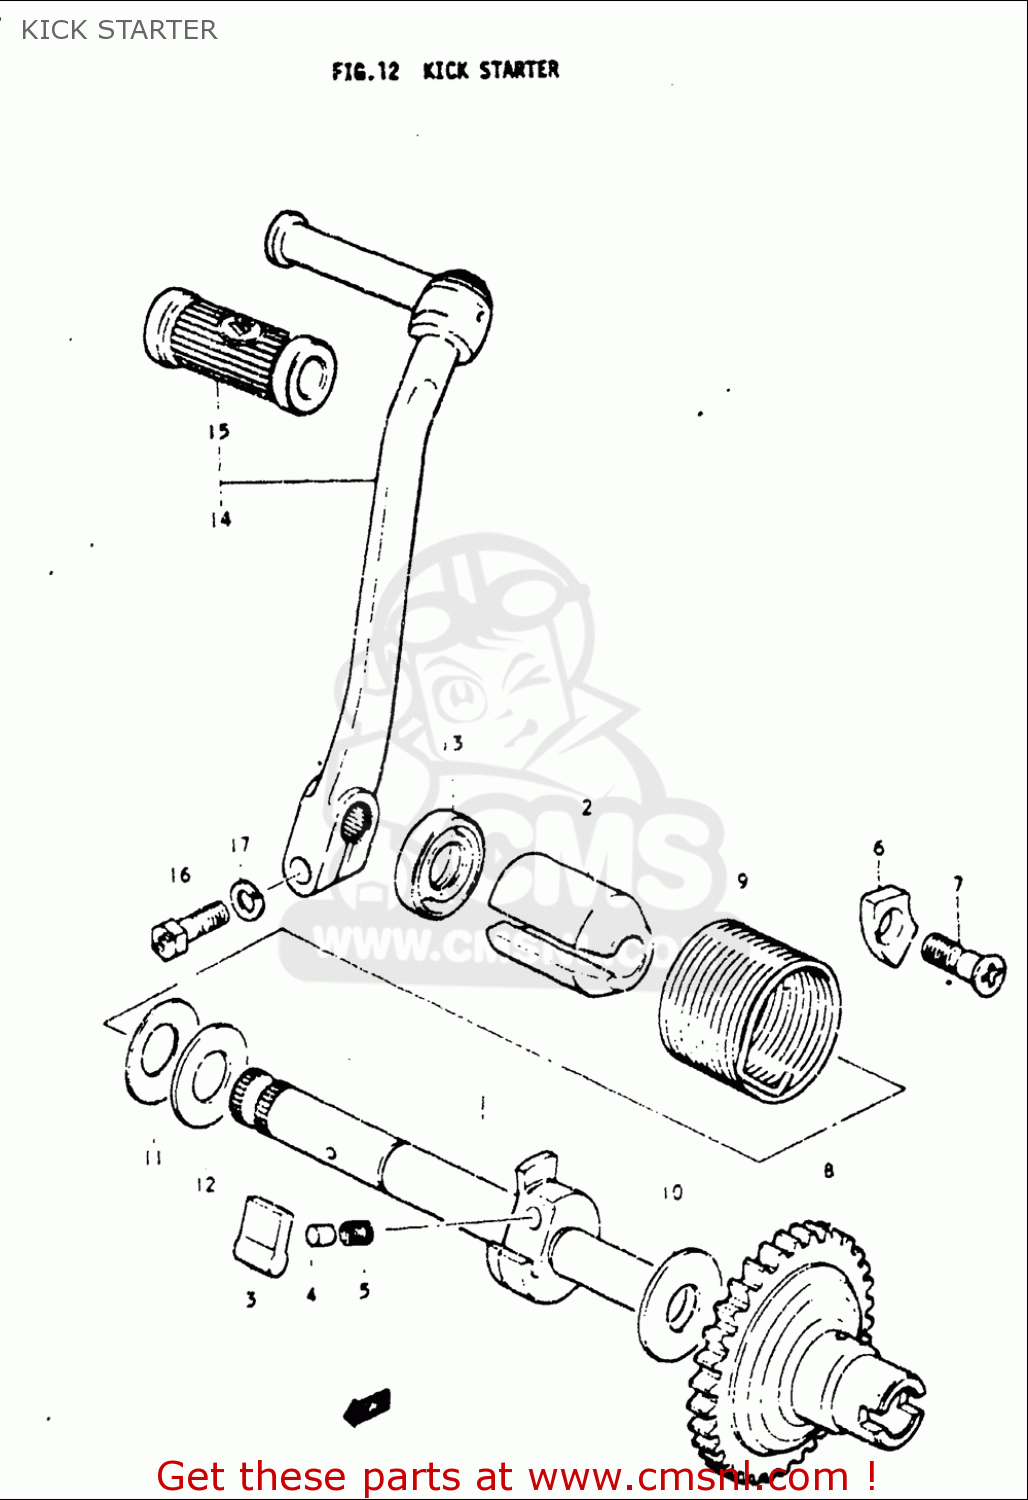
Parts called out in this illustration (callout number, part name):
1	SHAFT,KICK STARTER
2	GUIDE,KICK STARTER SFT SPRING
3	PAWL,KICK STARTER
4	PIN(5X15.5)
5	SPRING
6	LIFTER,KICK STARTER PAWL
7	SCREW(6X19)
10	WASHER
11	WASHER
12	WASHER(16X30X0.5)
13	SEAL,OIL(16X30X8)
14	LEVER ASSY,KICK STARTER
15	RUBBER,KICK STARTER PEDAL
16	BOLT
17	WASHER,LOCK
